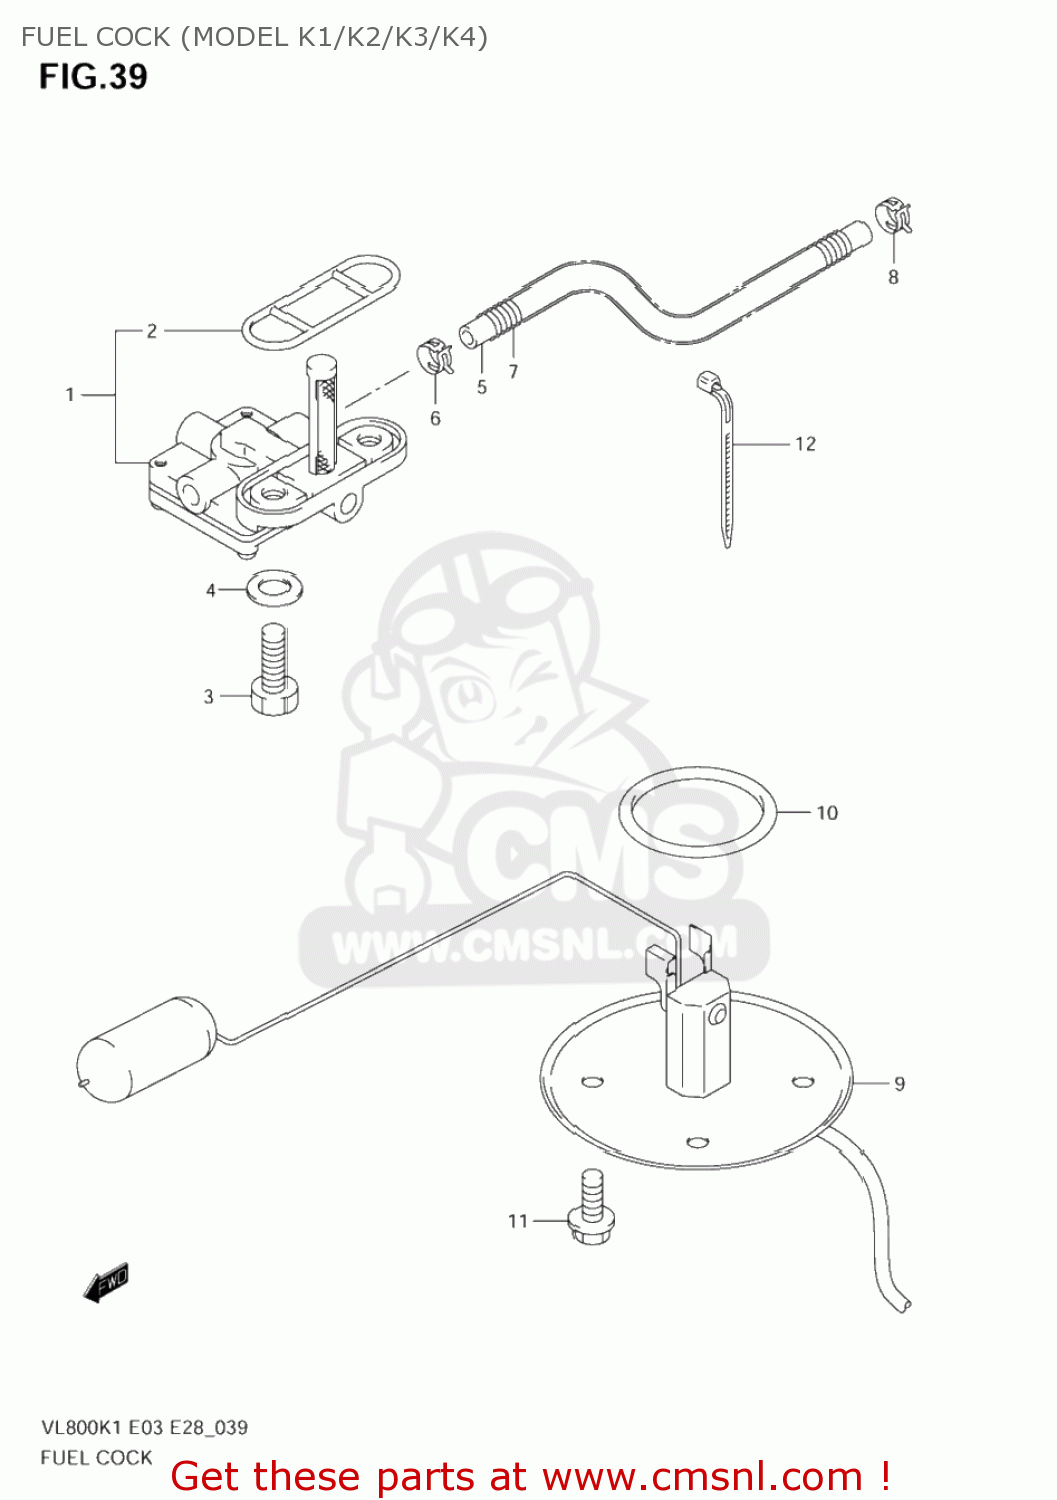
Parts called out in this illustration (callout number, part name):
1	COCK ASSY,FUEL
2	O RING,JOINT
3	BOLT(6X20)
4	GASKET(6.4X11.5X0.8) (NAS)
5	HOSE
6	CLIP
7	SPRING
8	CLIP
9	GAUGE ASSY,FUEL LEVEL SENDER
10	O RING
11	BOLT
12	CLAMP(L:45)
